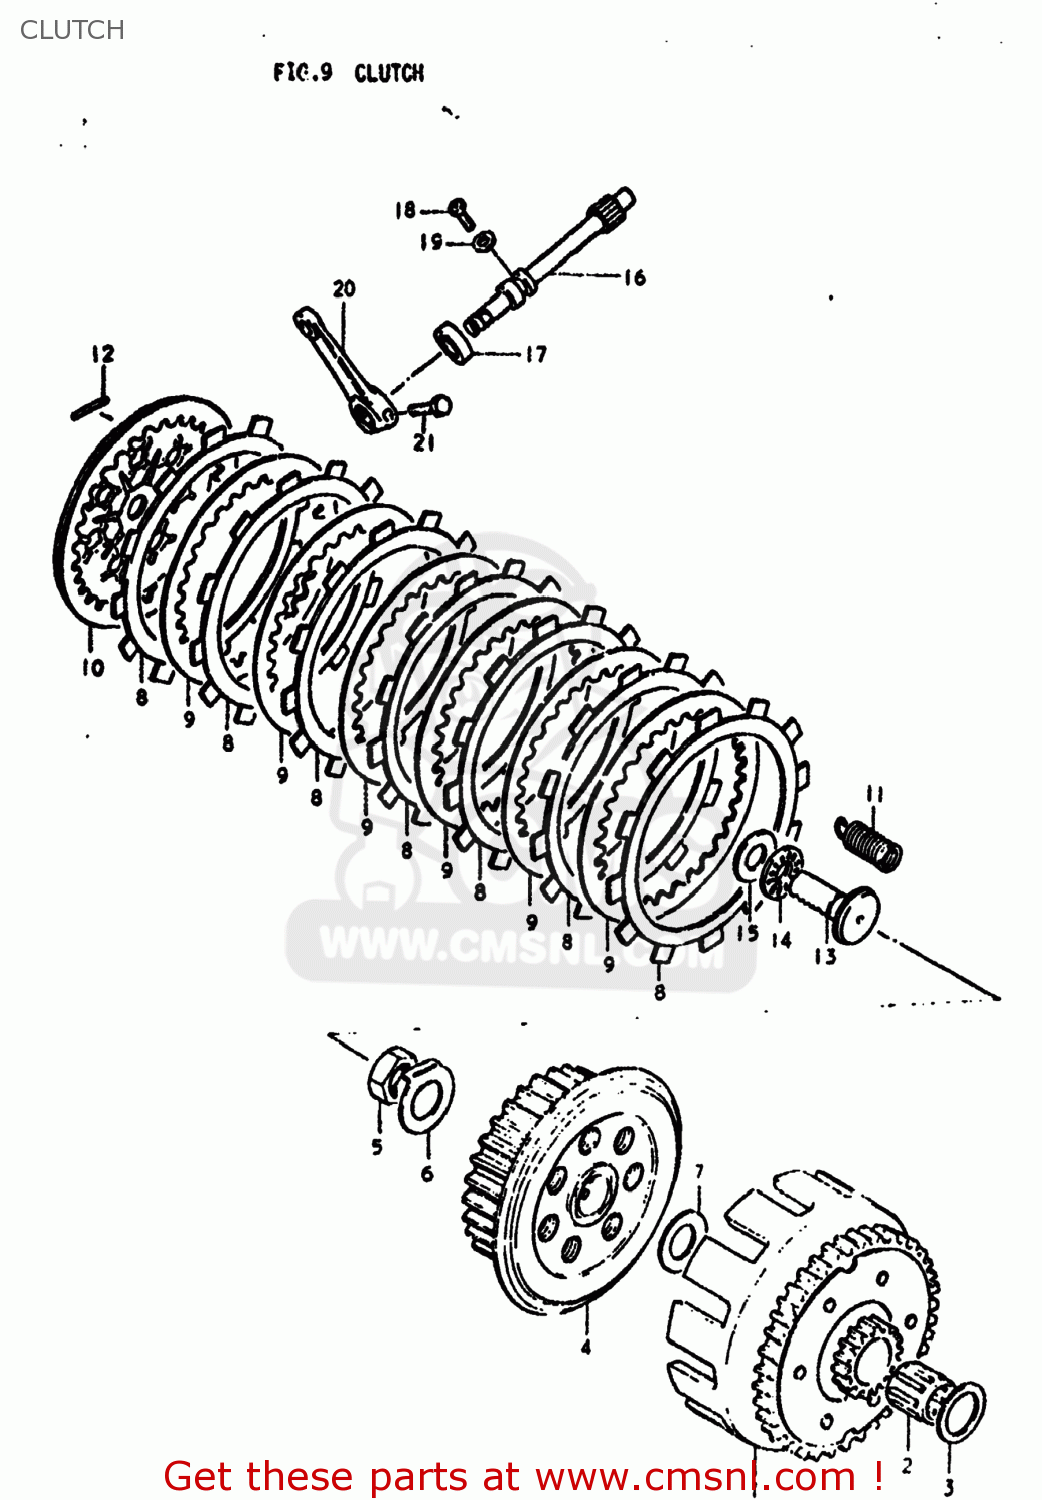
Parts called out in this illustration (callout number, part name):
1	GEAR ASSEMBLY,PRIMARY DRIVE
2	BEARING(20X25X26)
3	WASHER
4	HUB,CLUTCH SLEEVE
5	NUT
6	WASHER,LOCK
7	WASHER
8	PLATE,CLUTCH DRIVE
9	PLATE,CLUTCH DRIVEN
10	PLATE,CLUTCH PRESSURE
11	SPRING
12	PIN(2.5X19.8)
13	RACK,CLUTCH RELEASE
14	BEARING(10X22X2.8)
15	WASHER
16	PINION,CLUTCH RELEASE
17	SEAL,OIL (10X17X5)
18	BOLT(6X12)
19	WASHER
20	ARM,CLUTCH RELEASE
21	BOLT
